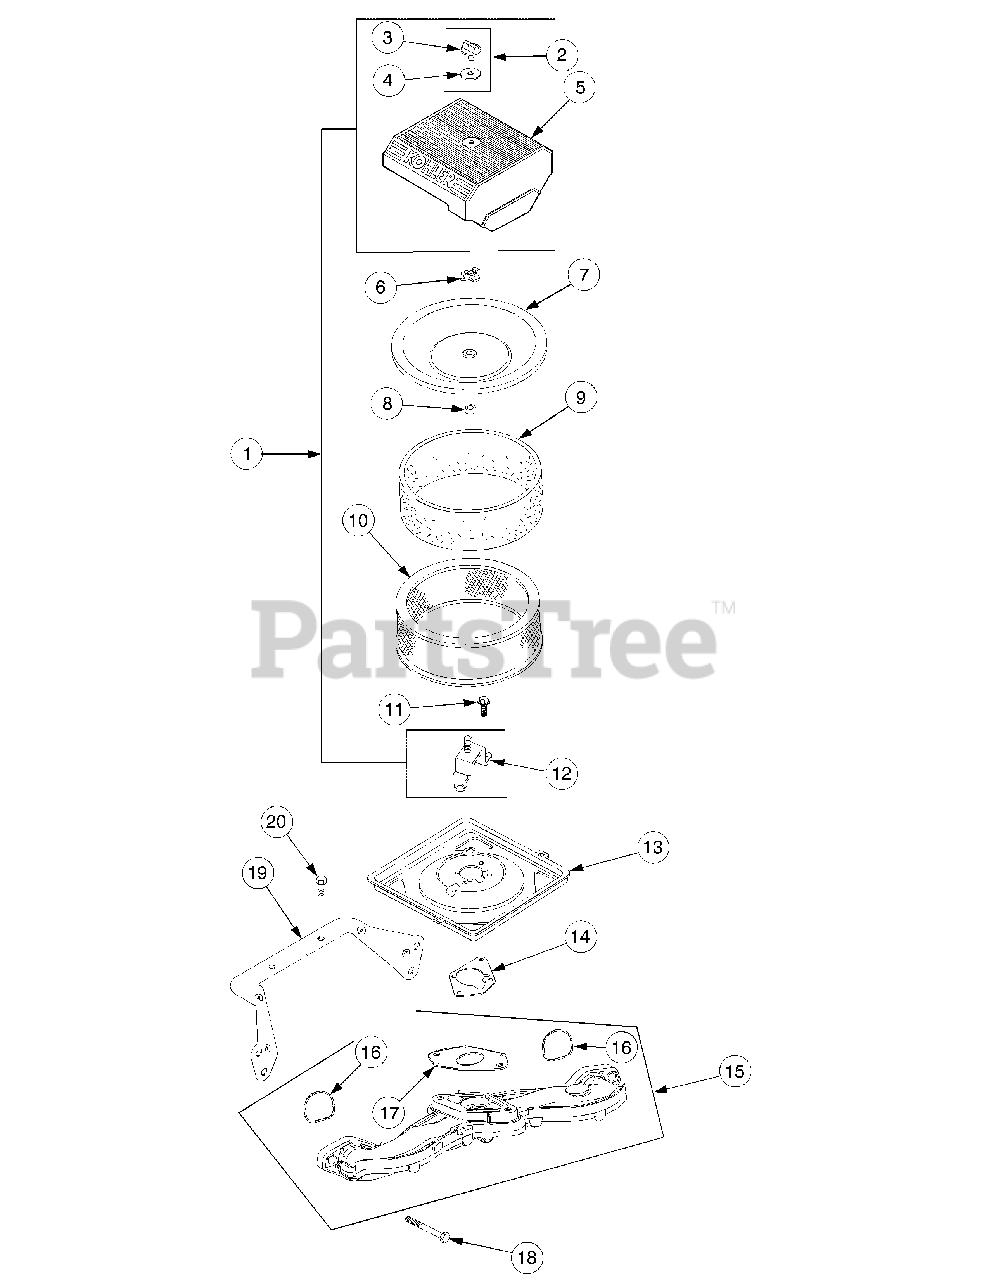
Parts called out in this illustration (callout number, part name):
1	Kit, Air Cleaner Cover (Incl. 2-5, 12)
2	Kit, Knob w/Seal (Incl. Ref #2,3)
4	Seal, Air Cleaner Cover Knob
5	Cover, Air Cleaner
7	Cover, Inner Air Cleaner
8	Seal, Inner Air Cleaner
9	Precleaner, Element
10	Element, Air Cleaner
11	Screw, Hex Flng, M6 x 1.0 x 16
12	Bracket, Air Cleaner Base
13	Base, Air Cleaner
14	Gasket, Air Cleaner Base
15	Manifold, Intake (Includes 16,17)
16	O-Ring, Intake Manifold
17	Gasket, Carburetor
18	Screw, Hex Flange, M6 x 1.0 x 40
19	Bracket, Air Cleaner Base
20	Screw, Hex Flange, M5 x .8 x10
